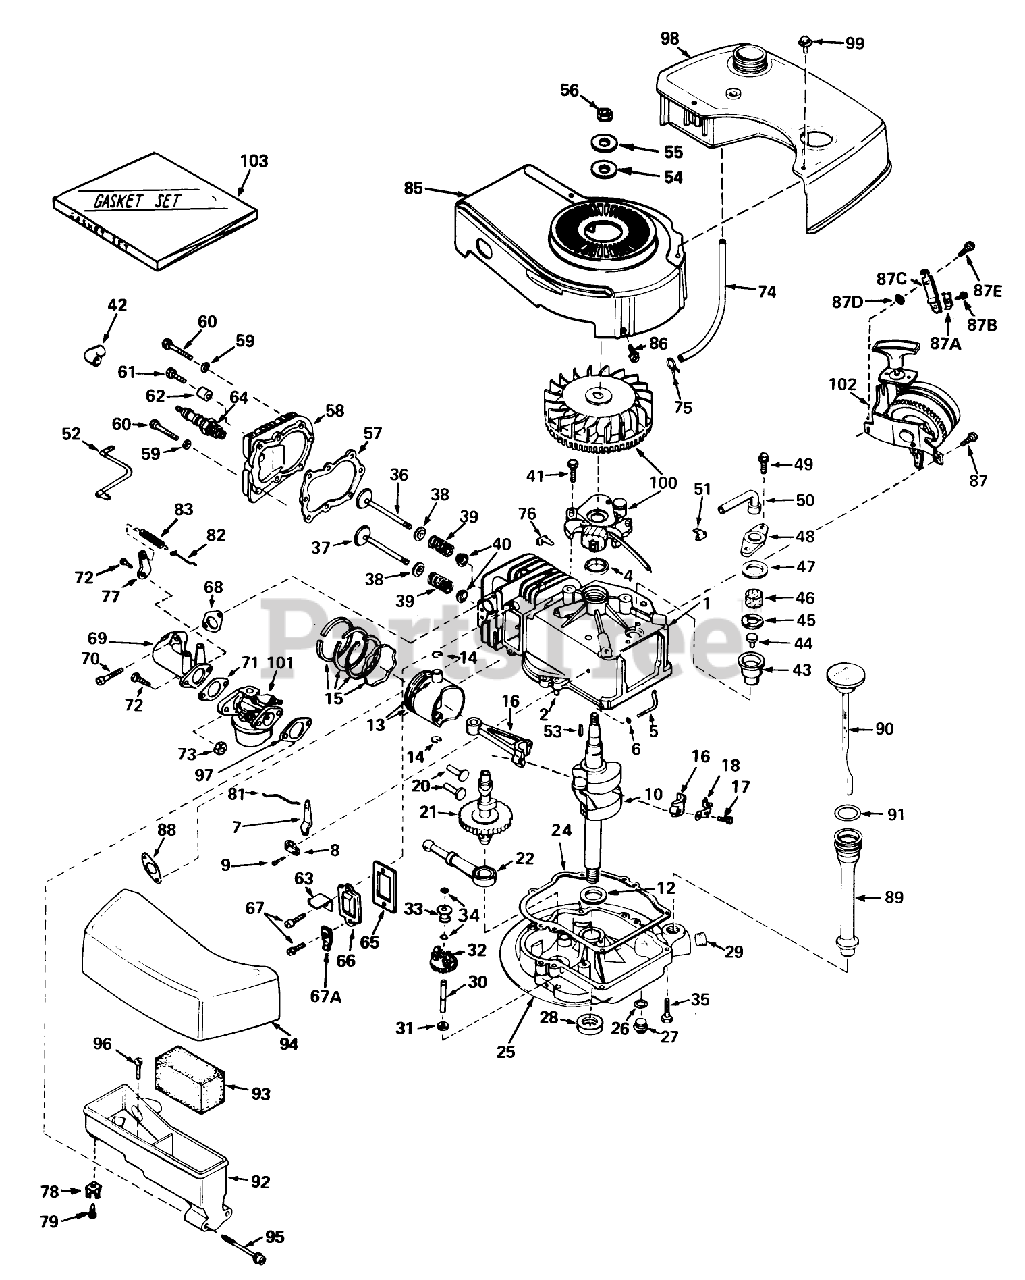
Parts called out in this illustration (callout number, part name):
1	Cylinder Assembly (Incl. Nos. 2, 4 87)
2	Pin-Dowel
4	Seal-Oil
5	Rod, Governor (Incl. No. 36)
6	Washer-Flat
7	Governor Lever
8	Clamp-Lever, Governor
9	Screw
10	Crankshaft
12	Washer-Thrust
13	Piston Pin Assembly (Incl. 2 of No. 14)(Std.)
13	Piston Pin Assembly (Incl. 2 of No. 14)(.010 Oversize)
13	Piston Pin Assembly (Incl. 2 of No. 14)(.020 Oversize)
14	Ring-Retaining, Piston Pin
15	Ring Set-Piston Std.
15	Ring Set-Piston .010 oversize
15	Ring Set-Piston .020 oversize
16	Rod Assembly, Connecting (Incl. Nos. 17 18)
17	Connecting Rod Bolt
18	Plate Lock
20	Lifter-Valve
21	Camshaft(Mech.Comp. Release)
22	Oil Pump ASM
24	Gasket, Mounting
25	Flange Assembly, Mounting (Incl. #27, 28, 29 30)
26	Gasket-Oil Drain
27	Plug Oil Drain
28	Seal-Oil
29	Plug Oil Drain
30	Shaft-Governor
31	Washer-Flat
32	Gear Assembly, Governor
33	Spool, Governor
34	Ring-Retaining
35	Screw (1/4-20 x 1-1/4)
36	Valve, Intake (Incl. Ref. #38, 39 40) (Std.)
36	Valve, Exhaust (1/32" Oversize) (Incl. Nos. 8, 9 10)
37	Valve, Exhaust (Standard) (Incl. Nos. 8, 9 10)
37	Valve, Exhaust (1/32" Oversize) (Incl. Nos. 8, 9 10)
38	Cap-Upper Valve Spring
39	Spring-Valve
40	Cap-Valve, Spring
41	Screw
42	Cover-Spark Plug
43	Body Breather Tube
44	Valve Check
45	2000A37 WIZARD ROTA
46	Element-Breather
47	Gasket-Breather
48	Cover Breather
49	Screw, Hex Hd. w/Conical
50	Tube, Breaker
51	Clip, Breather
52	Wire, Ground
53	Key Flywheel
54	Washer Flat
55	Washer, Belleville
56	Nut, Flywheel
57	Oil Fill Tube
58	Head Cylinder
59	Washer
60	Screw
61	Screw Hex Hd. Cap
62	Space
63	Retainer Clip
64	Plug, Spark (J17LM or equiv.)
65	Gasket-Breather
66	Cover-Valve
67	Screw
67A	Terminal
68	Gasket, Intake
69	Pipe, Intake
70	Screw (1/4-20 x 1)
71	Gasket-Carburetor
73	Nut and Lock Washer (1/4-28)
74	Line-Fuel
75	Clamp-Line, Fuel
76	Clip-Wire
77	Lever-Adjusting, R P M
78	Terminal
79	Screw
81	Link Governor
82	Link Governor Spring
83	Spring Governor
85	Housing, Blower
86	Screw
87	Screw (1/4-20 x 1/2)
87A	Conduit
87B	Screw (10-32 x 3/8)
87C	Bracker
87D	Washer
87E	Screw (1/4-20 X 5/8)
88	Gasket Exhaust
89	Tube, Oil Filler
90	Dipstick, OiI (Incl. No. 91)
91	O-Ring
92	Body Air Cleaner
93	Filer, Air
94	Cove, Air Cleaner
95	Screw Fil Hd.
96	Screw, Hex Hd.
97	Gasket-Air Cleaner
98	Tank Fuel
99	Screw (10-32 x 35/64)
100	LEVER
101	Carburetor
102	Starter
103	53024/VAR.16HP O/P
